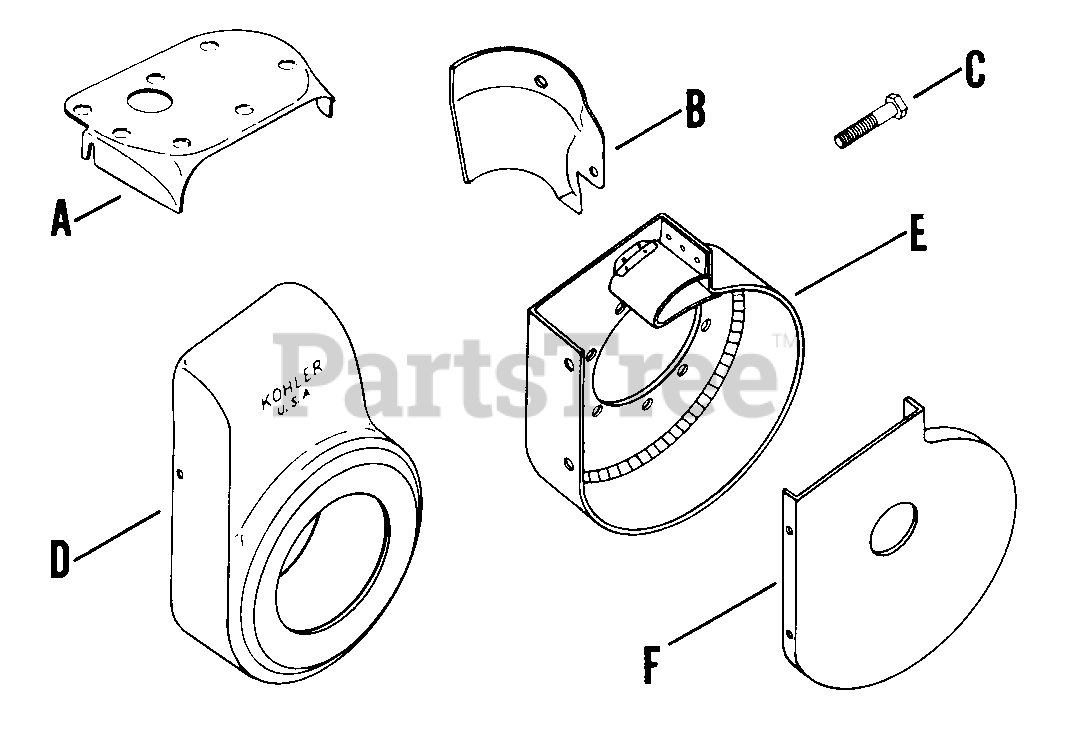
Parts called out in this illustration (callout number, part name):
A	BAFFLE, HEAD - (#DSC)
B	BAFFLE - DISCONTINUED
D	HOUSING - DISCONTINUED
